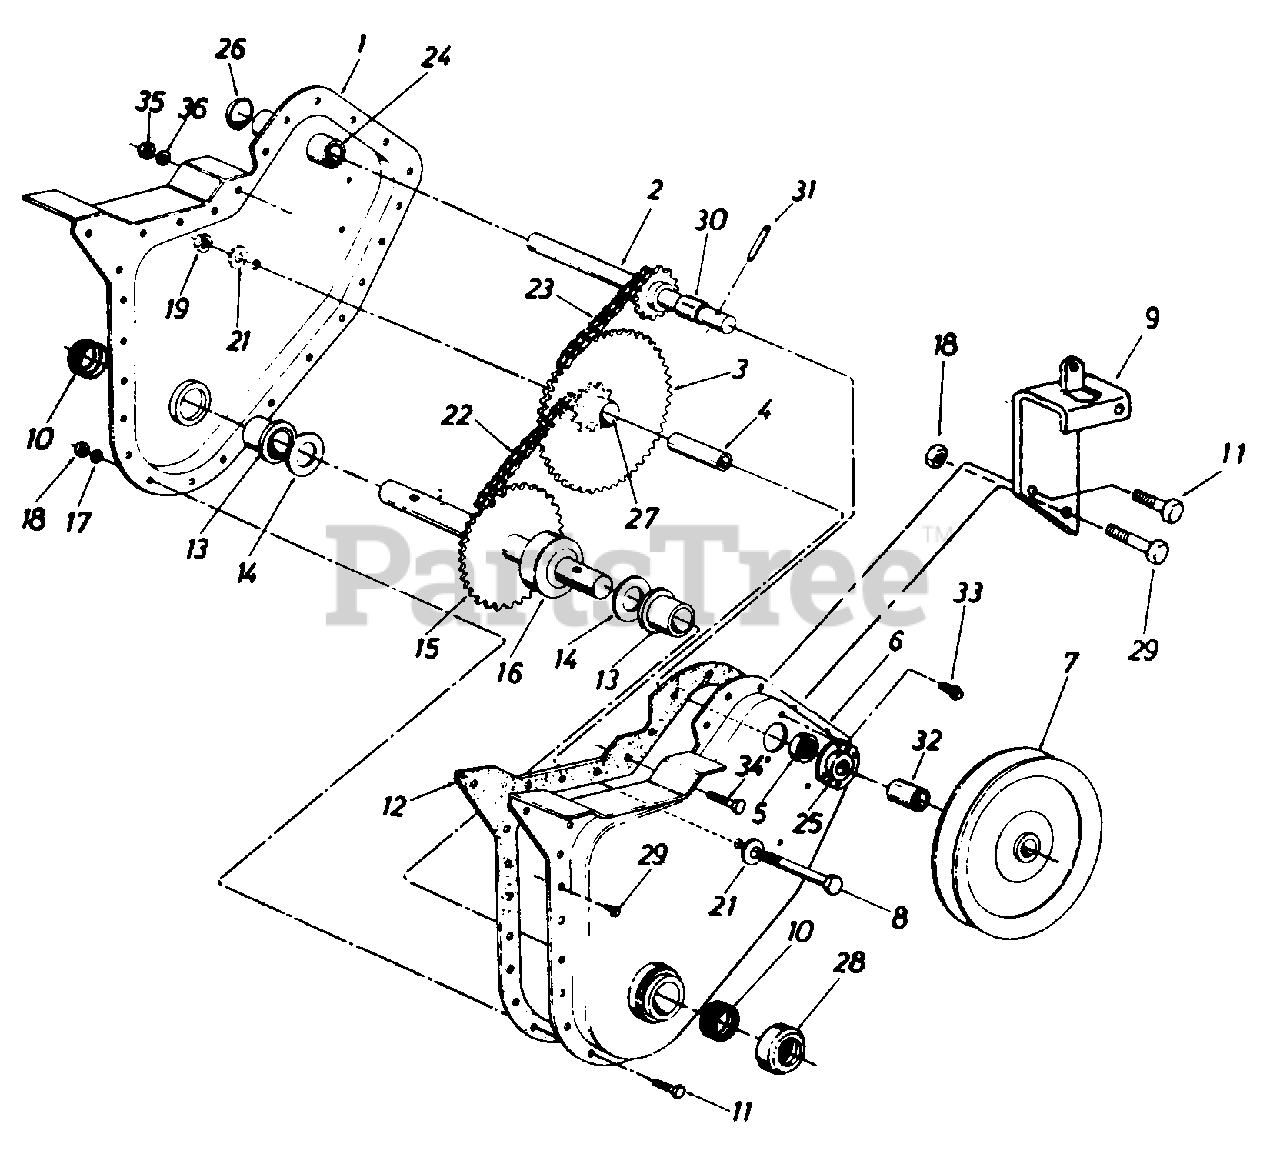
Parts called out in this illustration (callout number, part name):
1	Chain Case Ass'y. R.H.
2	Input Shaft Ass'y.
3	Hub and Sprocket Ass'y.
4	Bearing Inner Race
5	Ball Bearing
6	Chain Case Ass'y. L.H.
7	Pulley Chain Case
8	Hex Bolt 3/8-24 x 2.5" Lg.*
9	Fuel Tank Brkt.
11	Hex Bolt 1/4-28 x .625" Lg.*
12	Gasket
13	Flange Brg. .879" I.D.
14	Fl-Wash. .88" I.D. x 1.5"
15	Tine Shaft Ass'y.
16	Spacer 7/8" I.D.
17	L-Wash. 1/4" I.D.
18	Hex Nut l/4-28 Thd.
19	Hex Ins. L-Nut 3/8-24 Thd.
21	Bell-Wash. .406" I.D.
22	Chain #420 1/2" Pitch 38 Links
23	Chain #35 .375" Pitch 50Links
24	Bearing .62" I.D. x.813"
25	Bearing Housing
26	Expansion Plug 13/16" Dia.
27	Bearing
28	Dust Cap
29	Hex Wash. Hd. Self-Tap Scr. 1/4-20 x .50" Lg.
30	Spacer .63" I.D. x .77" O.D. x .38" Lg.
31	Spring Pin Spiral 1/4" Dia. x 11/2" Lg.
32	Spacer .647 x 1 25"
33	Hex Wash. Hd. Self-Tap Scr. 1/4-20 x .38" Lg.
34	Hex Bolt 5/16-18 x .75" Lg.*
35	Hex Nut 5/16-18 Thd.
36	L-Wash. 5/16" I.D.
